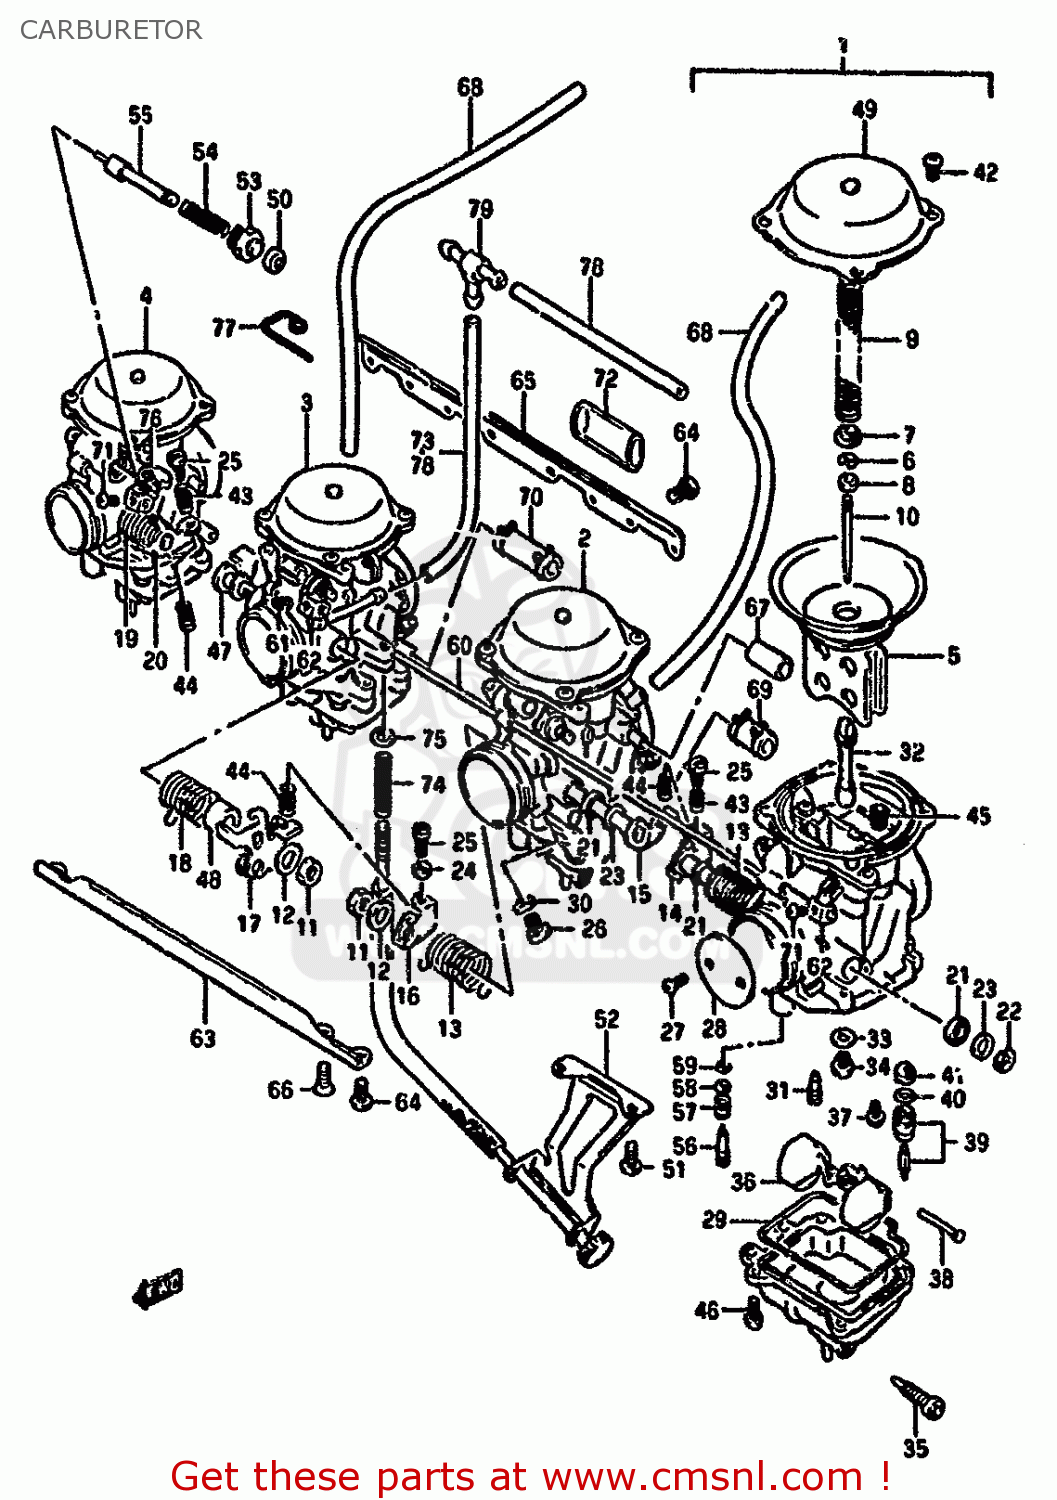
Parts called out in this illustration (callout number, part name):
1	CARBURETOR ASSY,LH
2	CARBURETOR ASSY,ML
3	CARBURETOR ASSY,MR
4	CARBURETOR ASSY,RH
5	5-2
6	7
7	8
8	RING
9	SPRING
10	10-2
11	12
12	WASHER
13	SPRING
14	SHAFT ASSEMBLY
15	SHAFT ASSEMBLY
16	LEVER
17	LEVER ASSEMBLY
18	SPRING
19	SPRING
20	SHAFT ASSEMBLY
21	SEAL
22	23
23	24
24	25
25	SCREW
26	SCREW
27	SCREW
28	VALVE,THROTTLE (130)
29	O RING,FLOAT CHAMBER
30	WASHER
31	JET,PILOT(42.5)
32	JET,NEEDLE(P-0)
33	WASHER,NEEDLE NOZZLE
34	35
35	SCREW
36	37
37	38
38	39
39	40
40	O-RING,NEEDLE VALVE
41	FILTER
42	SCREW
43	SPRING
44	SPRING,THROTTLE SCREW
45	46
46	SCREW
47	SHAFT ASSEMBLY
48	RING
49	COVER,DIAPHRAGM
50	51
51	52
52	BRACKET ASSY
53	GUIDE SCREW,PLUNGER
54	SPRING
55	PLUNGER ASSY
56	SCREW,PILOT
57	58
58	59
59	60
60	SHAFT,STARTER
61	SCREW
62	LEVER
63	PLATE
64	65
65	PLATE
66	67
67	68
68	HOSE
69	HOSE SET (3X5X18)
70	HOSE ASSY
71	SCREW,THROTTLE ADJUST
72	HOSE(16X19X100)
73	HOSE
74	SPRING
75	76
76	LEVER
77	CLIP
78	HOSE
79	NIPPLE
